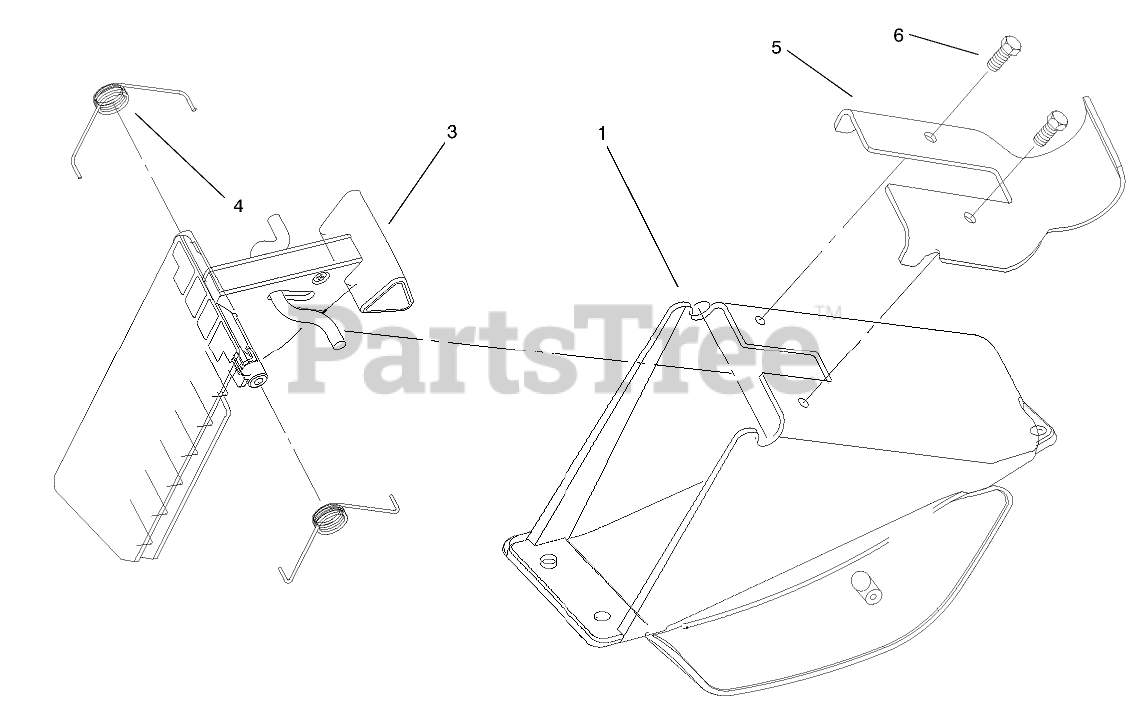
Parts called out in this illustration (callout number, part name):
1	CHUTE - DISCHARGE
3	ASM - DISCHARGE DOOR
4	SPRING-DOOR, RH
5	CHUTE PLATE ASM
6	SCREW-PLASTITE
